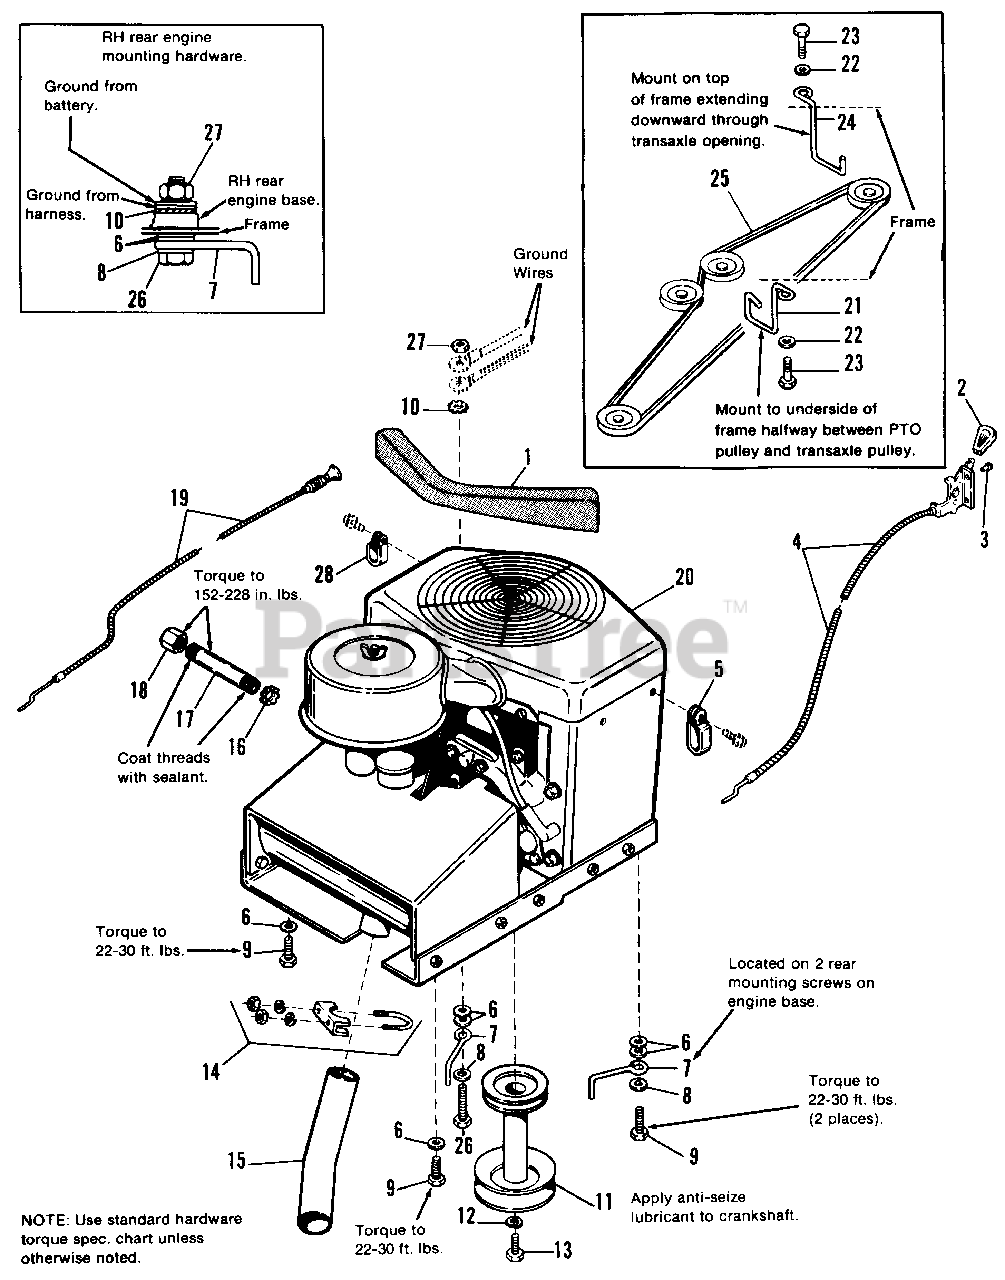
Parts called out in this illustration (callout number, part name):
1	BAFFLE, Engine, Top
2	KNOB, Throttle
4	CONTROL ASSY., Throttle
5	CLAMP, Cable
6	WASHER, 3/8
7	BELT Stop
8	WASHER, 3/8
9	SCREW, Taptite, 3/8-16 x 1-1/2 (Zinc Pltd.)
10	LOCKWASHER, Ext. Tooth, 3/8
11	PULLEY ASSY., Engine
12	LOCKWASHER, 7/16
13	CAPSCREW, Hex, 5/16-20 x 1-1/4
14	CLAMP, 1-1/2 Dia.
15	EXTENSION, Muffler
16	LOCKNUT, Conduit
17	OIL DRAIN
19	CABLE, Choke
20	ENGINE ASSY., Kohler 17 HP
21	GUIDE, Belt
23	SCREW, Taptite, 5/16-18 x 5/8
24	GUIDE, Belt
25	BELT, "V", Transmission Drive
26	SCREW, Taptite, 3/8-16 x 2 (Zinc Pltd.)
27	NUT, Hex, Full, 3/8-16 (Zinc Pltd.)
28	CLAMP, Cable
